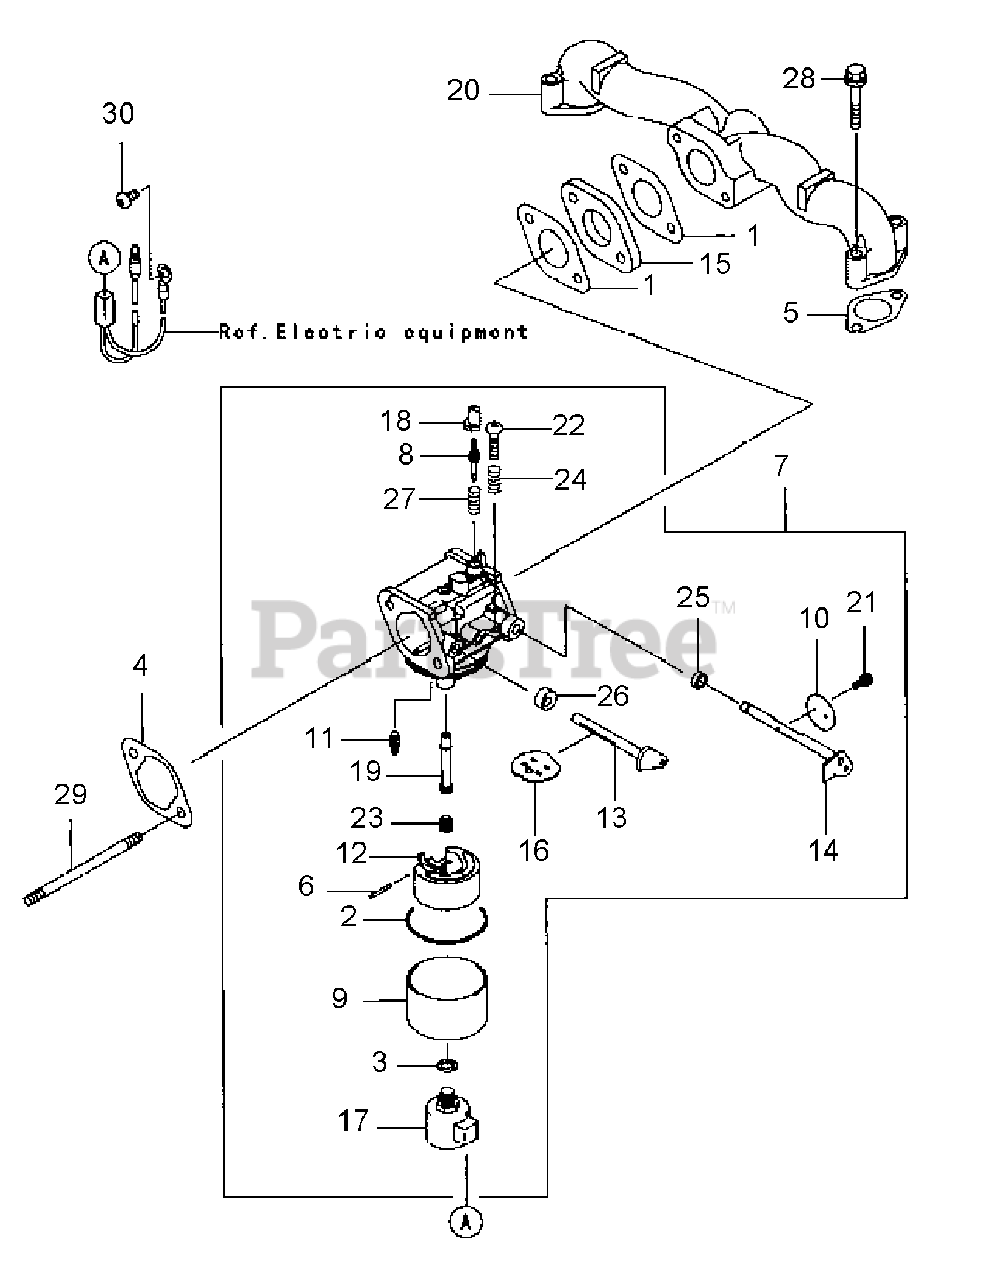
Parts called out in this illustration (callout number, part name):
1	INSULATOR GASKET
2	CHAMBER GASKET
4	AIR CLEANER GASKET
7	CARBURETOR ASSY.
8	PILOT AIR SCREW
10	THROTTLE VALVE
14	THROTTLE SHAFT
15	INSULATOR
16	CHOKE VALVE ASSY.
20	INTAKE MANIFOLD
23	MAIN JET #112
28	FLANGED BOLT
